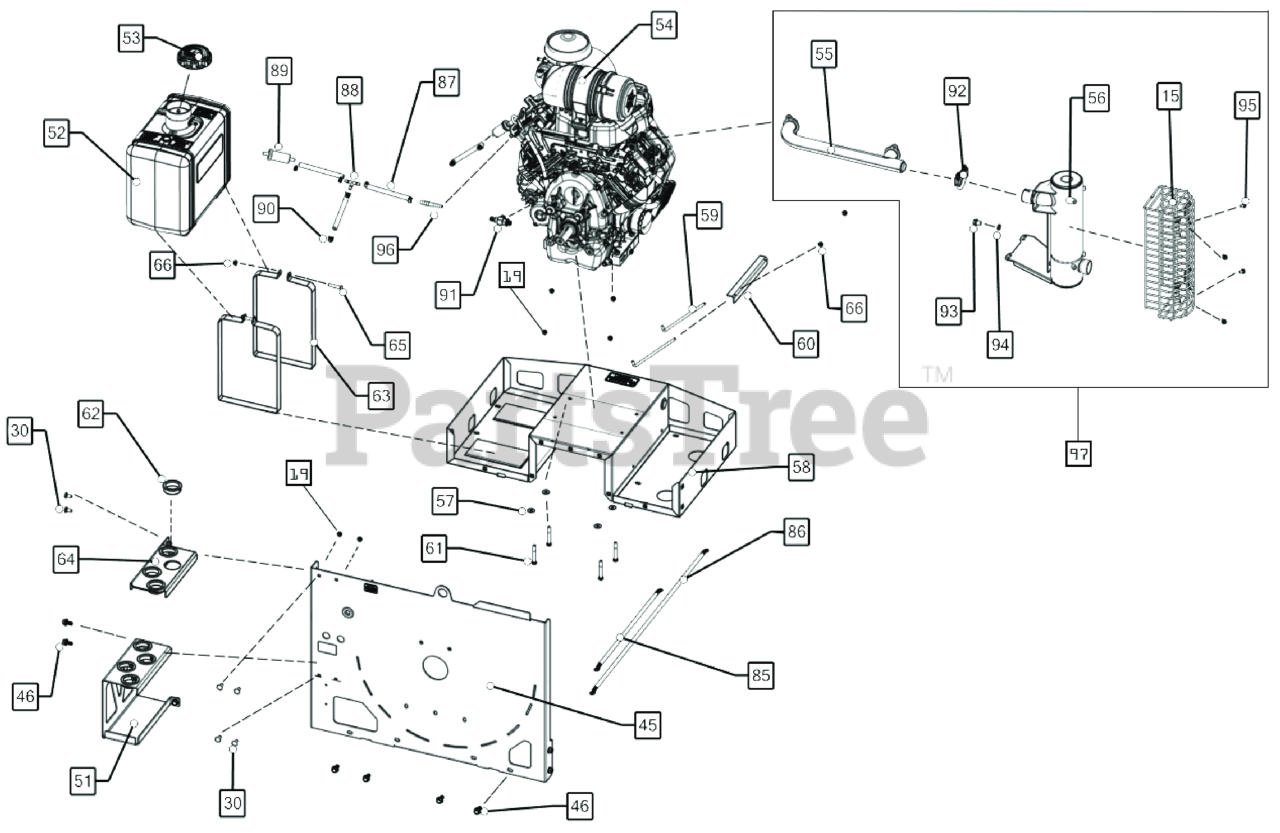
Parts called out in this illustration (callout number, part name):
15	GUARD MUFFLER DL35
19	NUT-HEX-NYLK, FLG .3125-18 ZP
30	BOLT CARRIAGE 5/16"-18 X 3/4" ZP
45	HOUSING WA DL29/37
46	SER HEX WASHER 3/8" - 16
50	MUFFLER ASSY DL29/37
51	RAKE HOLDER, LOWER DL
52	TANK & CAP ONLY - SIX GALLON 2.500" NECK
53	CAP, CARB/EPA 3.500"
54	ENGINE 29HP HORZ. SHAFT B&S
55	MANIFOLD DL35
56	MUFFLER DL29/37
57	WASHER 5/16" FLATWASHER Z/P
58	ENGINE 29HP HORZ. SHAFT B&S
59	ROD BATTERY HOLD DOWN
60	BRACKET BATTERY
61	SCREWCAP 5/16"-18X2 1/4" HCS ZP
62	BUSHING, SNAP 1.81" ID
63	CLAMP, TANK FUEL
64	RAKE HOLDER, UPPER DL
65	BOLT CARRIAGE 1/4-20 X 1 3/4 Z/P
66	NUT-HEX-NYLK, FLG .250"-20 ZP
84	BOLT CARRIAGE 5/16"-18 X 3/4" ZP
85	CABLE BATTERY BLACK 20"
86	CABLE BATTERY 36"
87	FUEL LINE 1/4" ID X 6"
88	1/4" X 1/4" X 1/4" BARB TEE FITTING
89	FUEL FILTER BRIGGS
90	CLAMP, FUEL LINE 0.50"
91	PLUG OIL DRAIN DL35
92	CLAMP MUFFLER DL35
93	O2 SENSOR PORT PLUG DL29
94	GSKT CRUSHABLE CPR 12MM X 18MM X 2MM THK
95	SCREW MUFFLER DL35
97	DL 29/35/37 MUFFLER ASSY SERVICE
